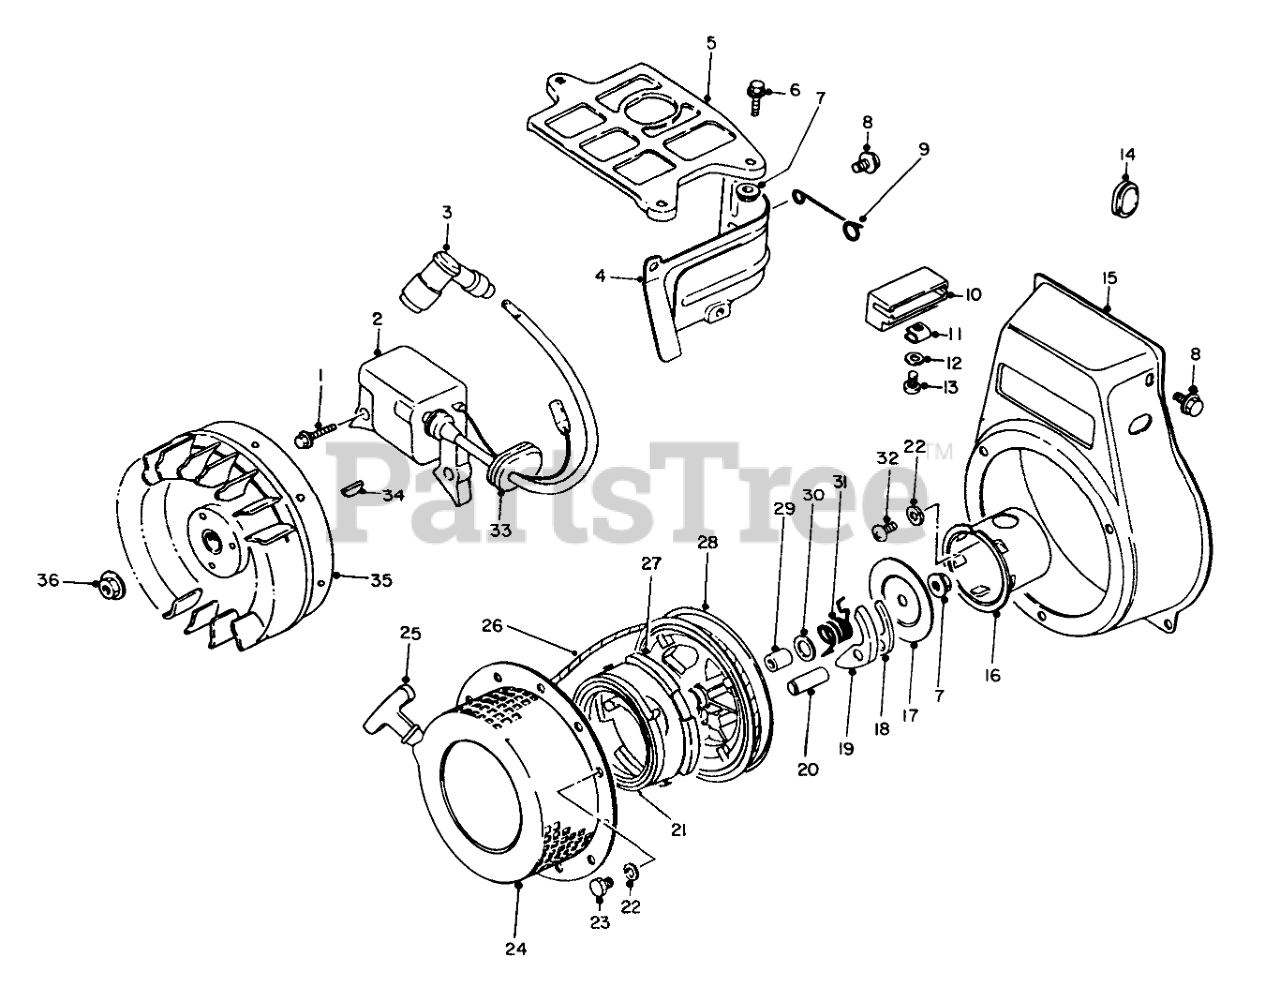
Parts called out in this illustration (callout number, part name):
2	Coil-Primary
3	SPARK PLUG CAP
4	Cowling-Side
5	Cowling-Upper
9	CLAMP
10	Holder-Lead Connector
12	Washer
14	Plug-High Tension Cord Hole
15	Cover-Cooling Fan
16	Pulley-Starter
17	Plate
18	Ratchet
19	Ratchet
21	SPRING
22	LOCKWASHER
24	Starter Assembly-Recoil (Incl. Ref. #7, 17-23 & 25-31)
25	Grip Assembly (Incl. Ref. #26)
26	Rope
27	SPRING CASE
29	Cover
30	Plate-Slide
31	Spring
32	Screw
33	Grommet
35	Flywheel
36	Nut
